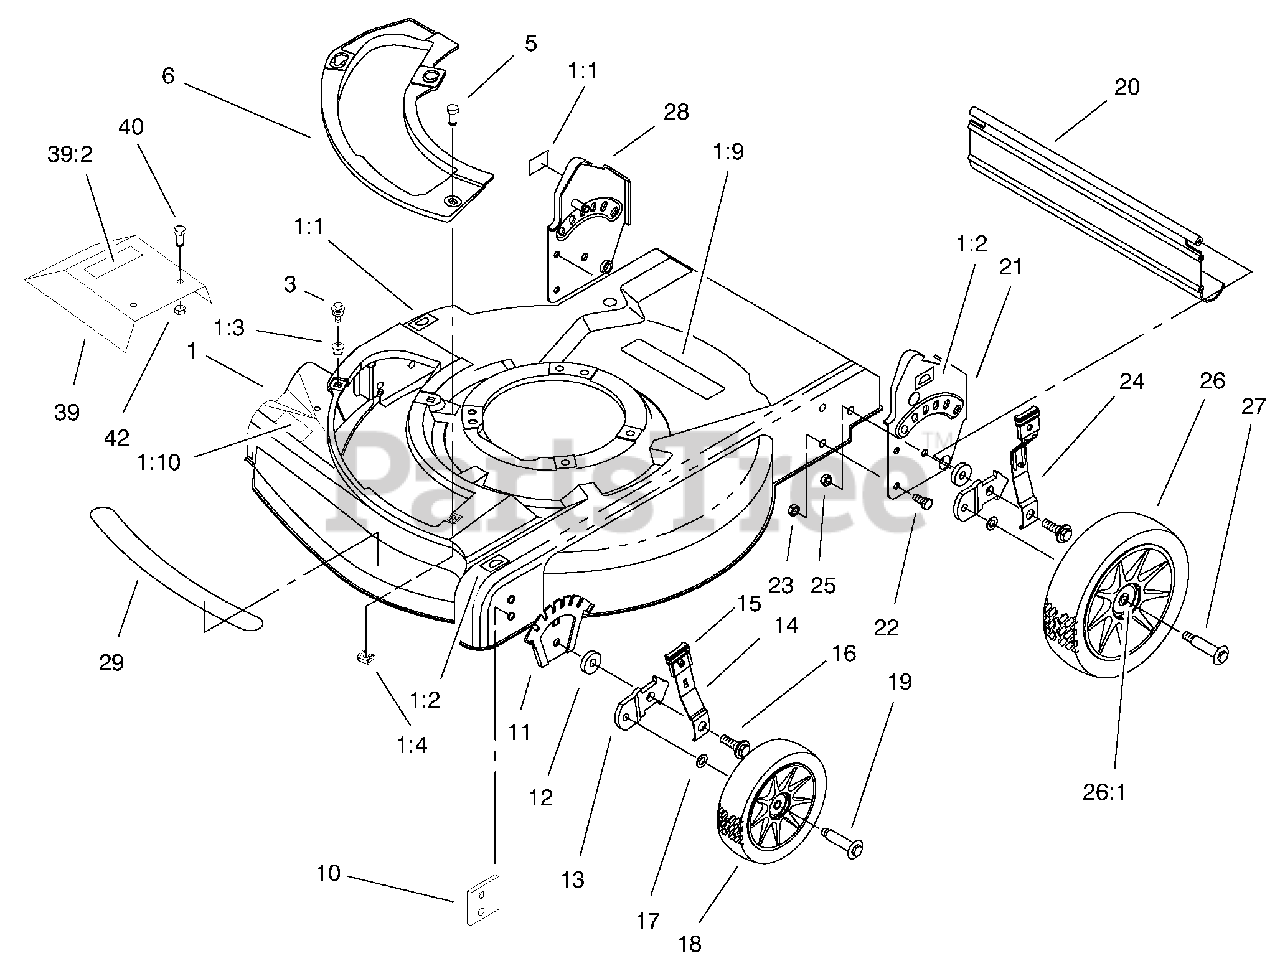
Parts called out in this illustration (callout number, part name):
1	Housing ASM
1:1	Decal-HOC
1:2	Decal-HOC
1:3	Grommet-Plastic
1:4	Nut-Cage
1:9	Decal-Danger
1:10	Decal-Danger
3	Screw-Sems
5	Screw-HH
6	Plate-Cover
10	Plate-Baffle
11	Plate-Height Adjust
13	Bracket-Wheel Height Adj
14	Spring Arm-Front
15	Knob-Height Adjust
16	Bolt-Shoulder
18	Wheel & Tire ASM
19	Bolt-Shoulder
20	Shield-Trailing
21	Handle Bracket ASM
22	Screw-HH
23	Nut-Lock
24	ASM-Spring Arm
25	Nut-Lock
26	ASM-Wheel
27	Bolt-Shoulder
28	RH Handle Bracket ASM
29	Decal-Deck 345vp
39	Guard-Plate
39:2	Decal-Warning
42	Nut-Lock
